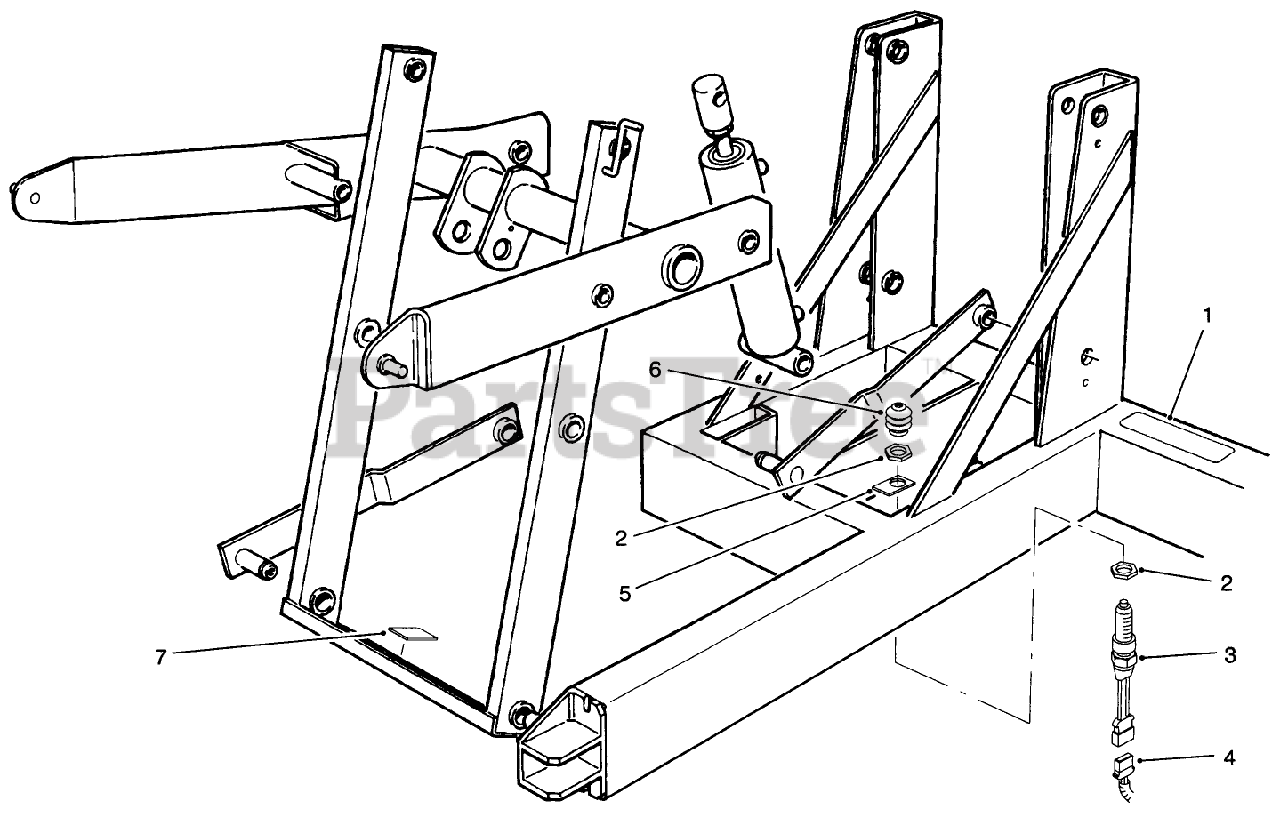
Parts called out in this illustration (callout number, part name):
1	DECAL - DANGER
2	NUT-HH
3	Switch Assembly (Incl. Ref. #2 & 6)
4	HARNESS-SWITCH
5	BRACKET - SWITCH
6	Boot-Switch
7	PLATE - SWITCH
